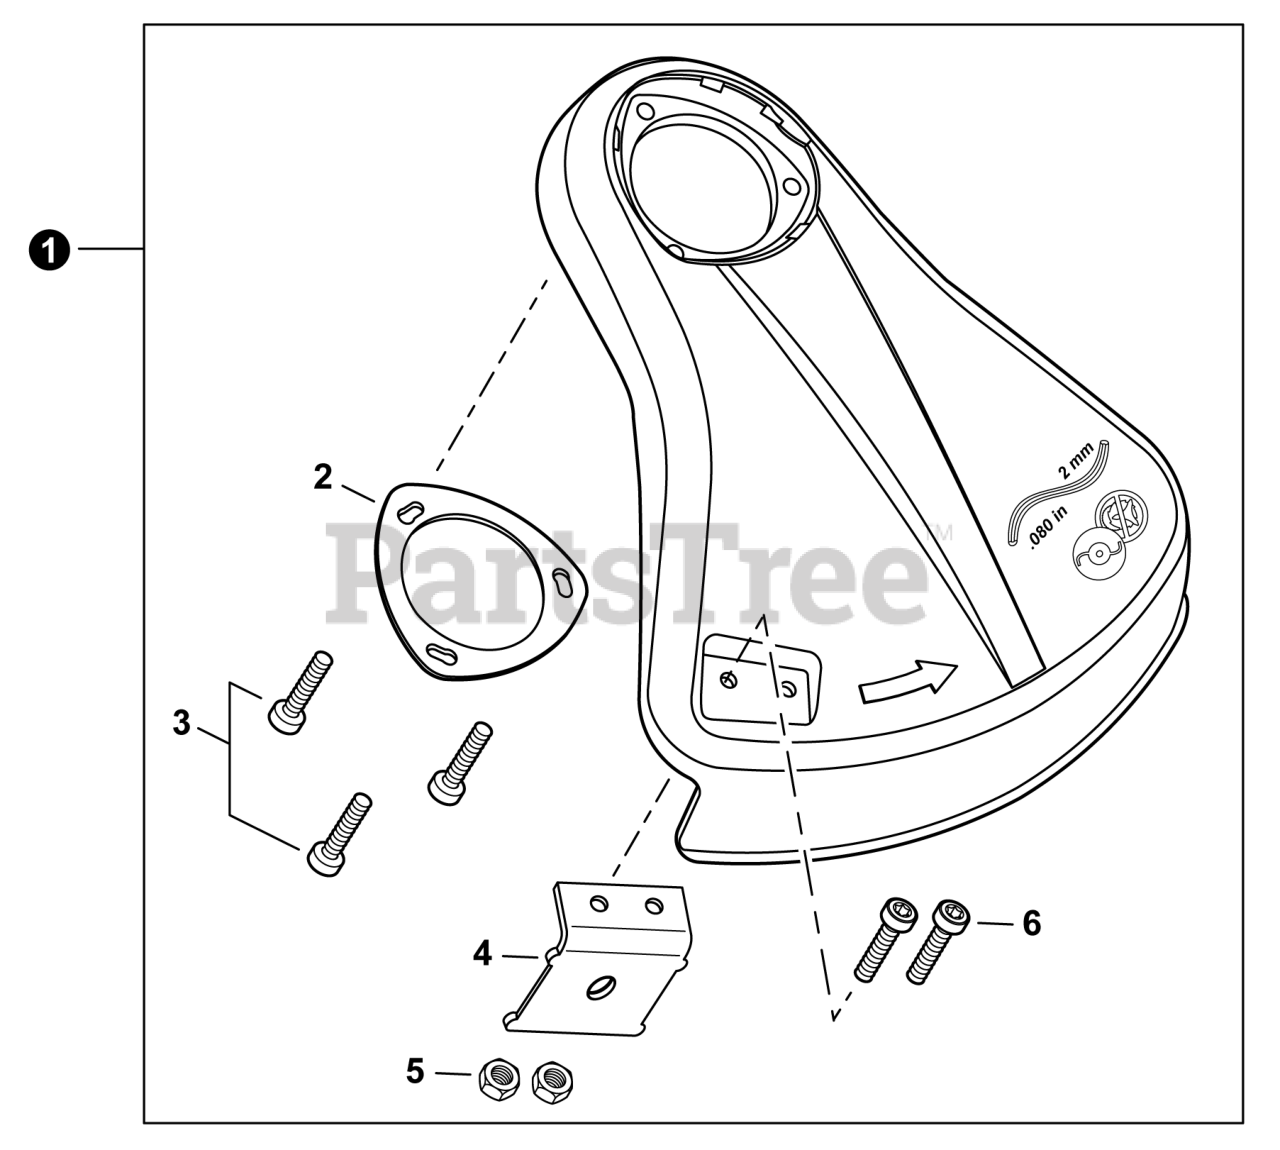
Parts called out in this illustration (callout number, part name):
1	DEBRIS SHIELD ASSY
2	PLATE, SHIELD
3	BOLT, TORX 5x16
4	CUTTER, NYLON LINE
6	BOLT, TORX 5x12
